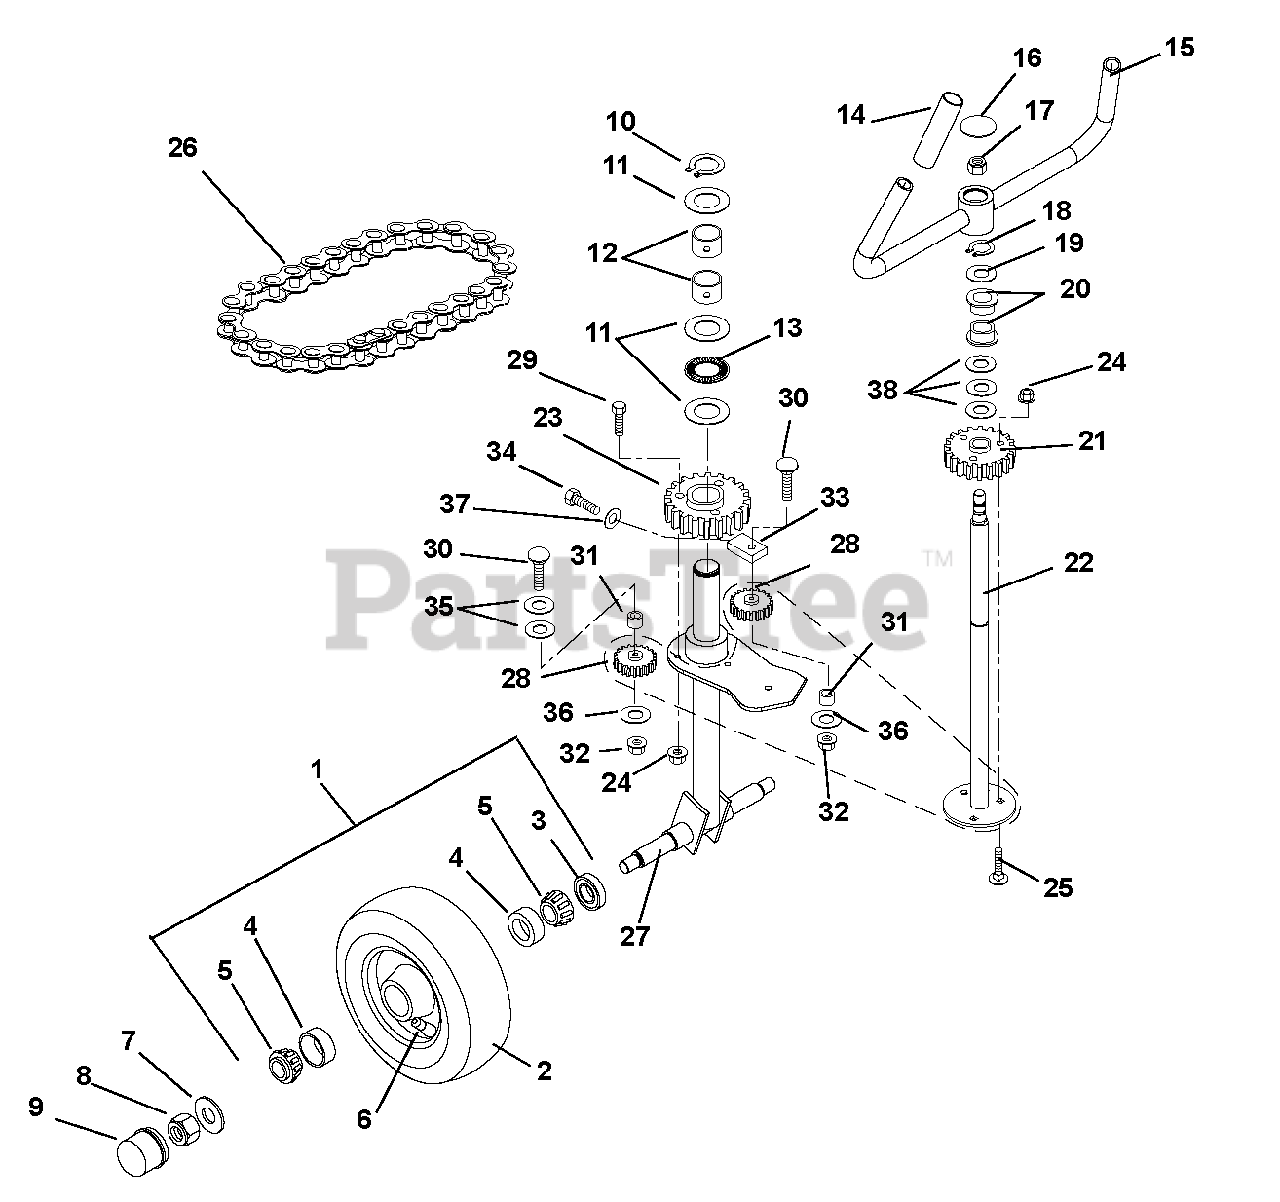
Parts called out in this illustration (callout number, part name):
1	Tire/Wheel Assembly, 16x6.50-8 (Contains Items 2 – 5)
2	Tire, 16 x 6.5-8
4	Bearing, Cup 1.980 x 4.20
5	Bearing, Cone with Grease
6	Valve Stem Assembly
7	Washer, Flat Steel .812 x 1.50 x .135
8	Nut, Locking Center .75-10
9	Cap, Dust
10	Ring, Retaining External 1.50 x 1.38
11	Washer, Thrust 1.502 x 2.18 x .063
12	Bearing, 1.00 x 1.135 x 1.002
13	Bearing, Needle Thrust 1.50 x 2.187 x .078
15	Weldment, Handlebar
16	Hole Plug 1.38
17	Nut, Locking Nylon .625-18
18	Ring, Retaining External .906 x .078
19	Washer, Thrust 1.55 x 1.002 x .093
20	Bushing, Flange 1.02 x 1.385 x .75 x 1.75
21	Sprocket, 23 Tooth #40
22	Weldment, Steering Shaft
23	Sprocket, 28 Tooth #40
24	Nut, Locking Top Flange .31-18
25	Bolt, Round Head Square Neck .31-18 x 1.50 Grade 5
26	Chain, #40 x 125 Pitches (62.5")
27	Weldment, Caster Wheel
28	Sprocket, #40 Idler
29	Bolt, Hex .31-18 x 1.75 Grade 5
30	Bolt, Round Head Square Neck .38-16 x 2.25 Grade 5
31	Spacer .406 x .625 x .656
32	Nut, Locking Top Flange .38-16
33	Plate, Idler Adjustment
34	Bolt, .31-24 x 1.50 Grade 8
35	Washer, Flat-Steel .406 x 1.125 x .25
36	Washer, Flat-Steel .406 x 1.375 x .135
37	Washer, Flat-Steel .344 x .688 x .065
38	Washer, Flat-Steel 1.12 x 1.500 x .092
